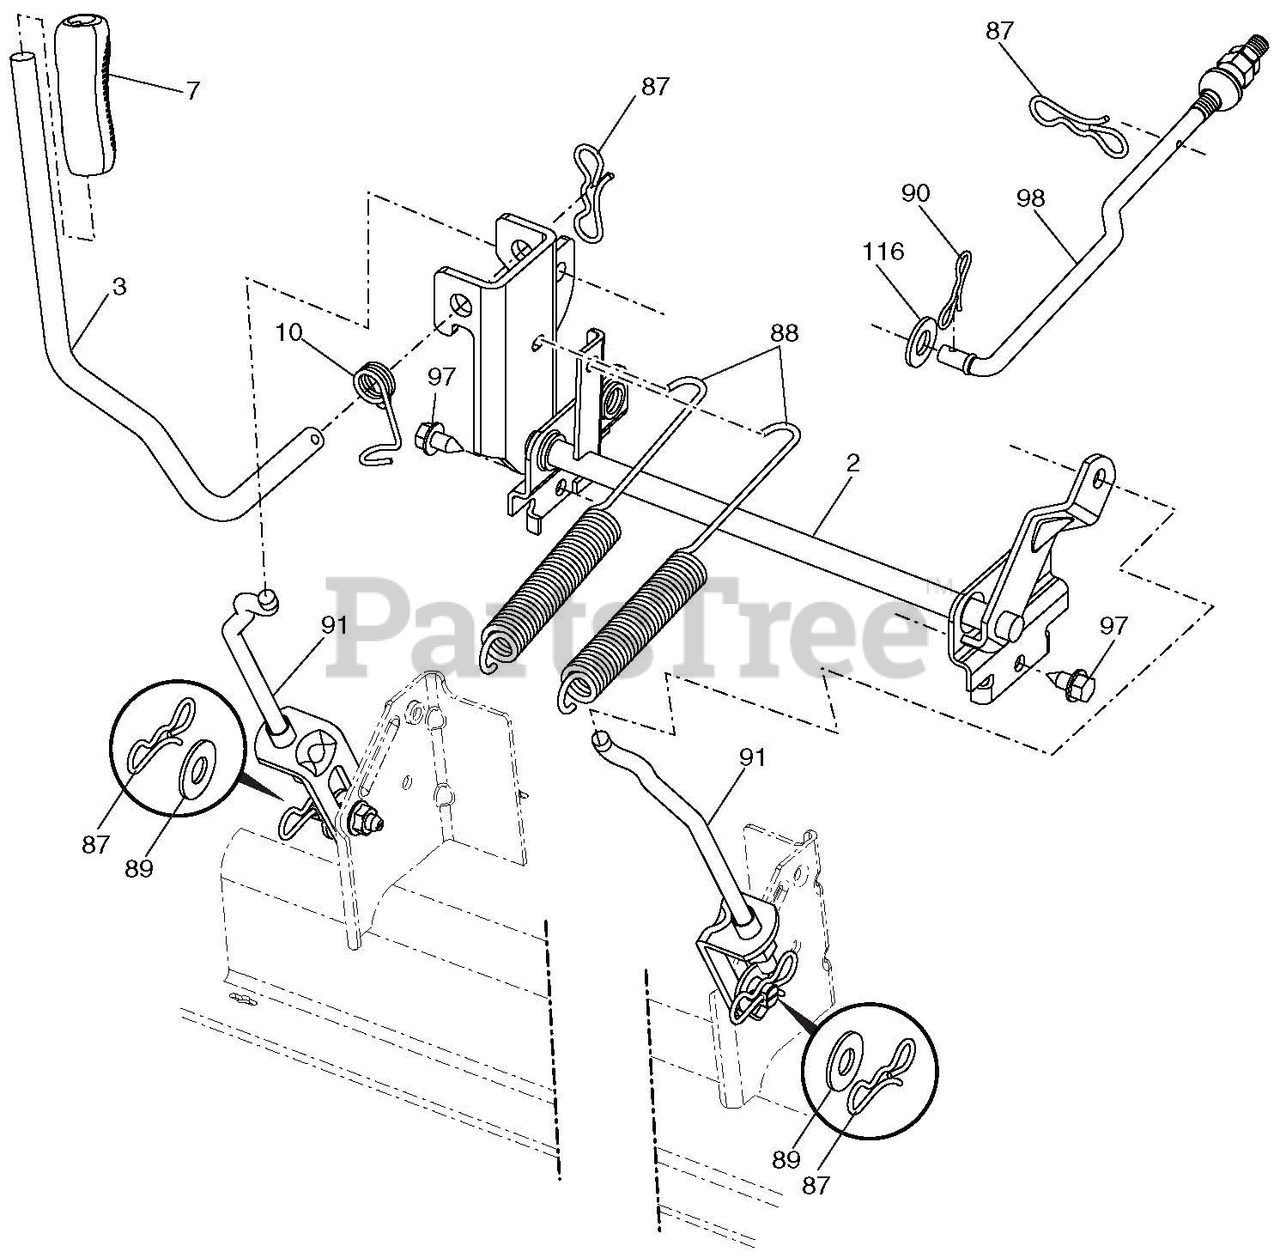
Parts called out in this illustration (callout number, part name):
2	SHAFT ASM.LIFT.CROSS.HD.
3	LEVER ASM., LIFT RH
7	GRIP LEVER 5625 LD BLACK 428
10	SPRING.TORSION.HANDLE.LIFT
87	PIN.COTTER.7/16.BOW TIE LOCK
88	SPRING LIFT ASSIST
89	WASHER.CLEAR ZINC
90	PIN.COTTER.5/16.BOW TIE LOCK
91	LINK ASM.LIFT.54"TG
97	SCREW.HEXWSH THDR3/8-16X3/4.BL
98	LINK ASM.SUSP.FRONT.MWR.10.5
116	WASHER 15/32 X 15/16 X 16 GA.
